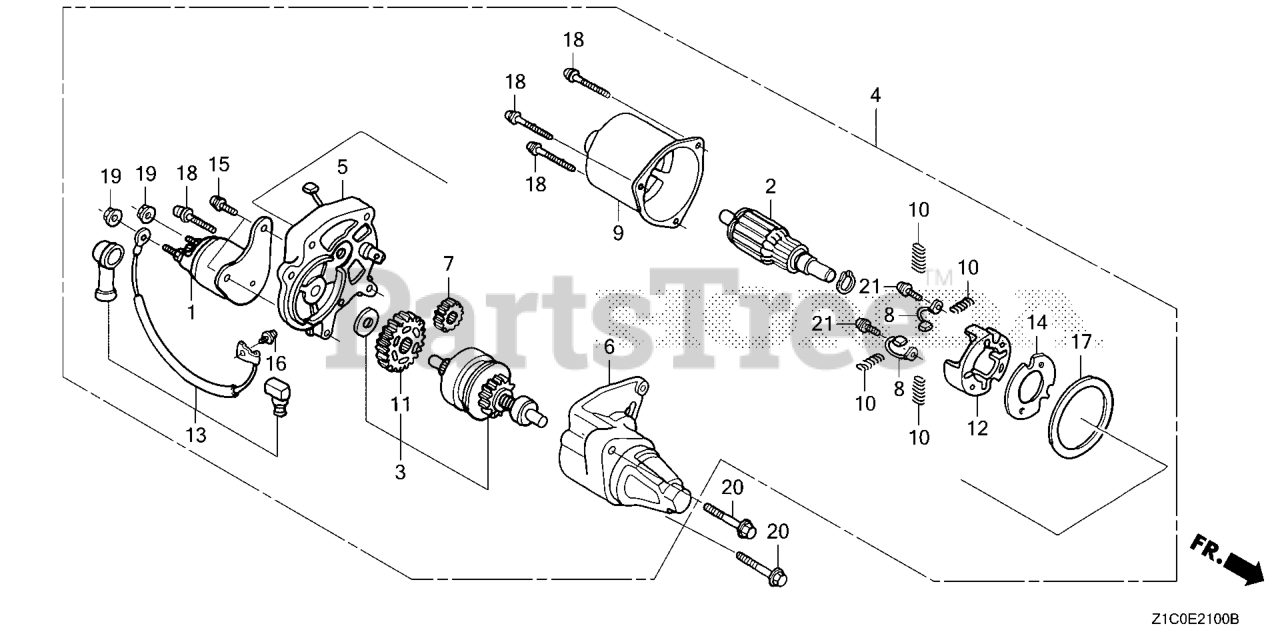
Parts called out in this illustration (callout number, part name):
1	CONTACTOR ASSY.
2	ARMATURE
3	CLUTCH, OVERRUNNING
4	STARTER MOTOR UNIT
5	BRACKET, CENTER
6	BRACKET, FR.
7	GEAR, DRIVE PINION
8	BRUSH
9	YOKE
10	SPRING, BRUSH RETURN
11	GEAR, REDUCTION
12	HOLDER, BRUSH
13	WIRE, WATER COVER
14	INSULATOR
15	BOLT-WASHER (5X14)
16	SCREW-WASHER (4X6)
17	GASKET
18	SCREW-WASHER (5X3)
19	NUT-WASHER (6MM)
20	BOLT, FLANGE (8X35)
21	SCREW-WASHER (4X14)
